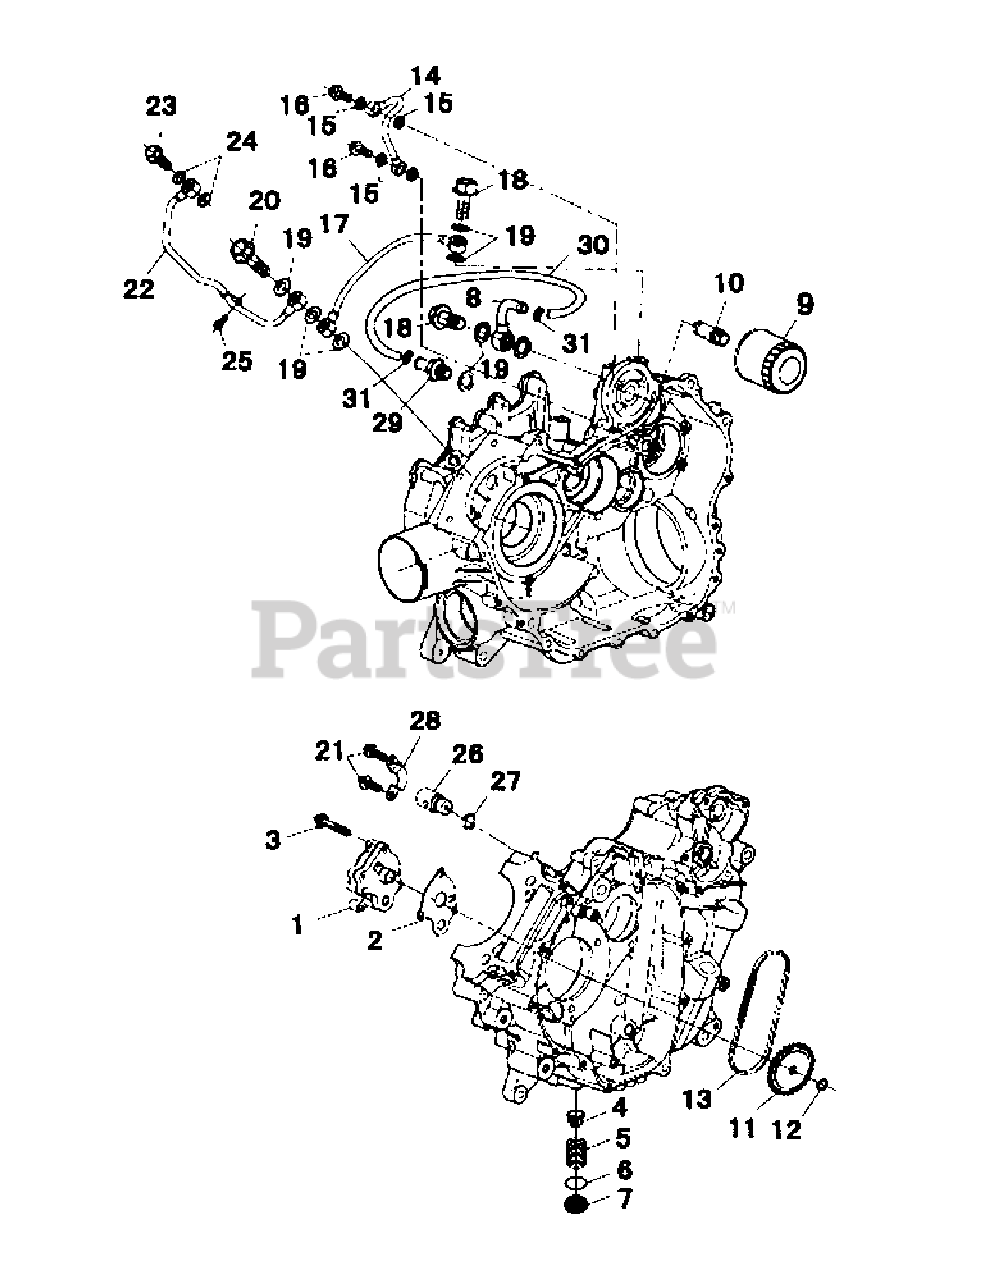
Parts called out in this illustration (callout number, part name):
1	Oil Pump-Comp
2	Paper Gasket-Oil Pump
3	Flangebolt M6X40
4	Oil Filter Net-Comp
5	O-Ring 14 X 2.3
6	Seal Cap Plug O-ring
7	Bolt M14X1.5X16
8	Fitting, Elbow Banjo
9	Oil Filter-Comp
10	Filter-Connecting Head
11	Sprocket-Drive
13	Chain-Oil Pump 04Ch-70
14	Pipe-Delivery I
17	Pipe-Delivery II
18	Bolt M14X1.5X28
19	Washer
20	Bolt M14X1.5X50
21	Flangebolt M6X14
22	Pipe-Delivery III
23	Bolt M10X1.25X30
25	Flangebolt M6X12
26	Relief Valve-Comp
27	O-Ring 10X2.45
28	Plate-Relief Valve
29	Fittings-Oil Cooler
30	Hose
